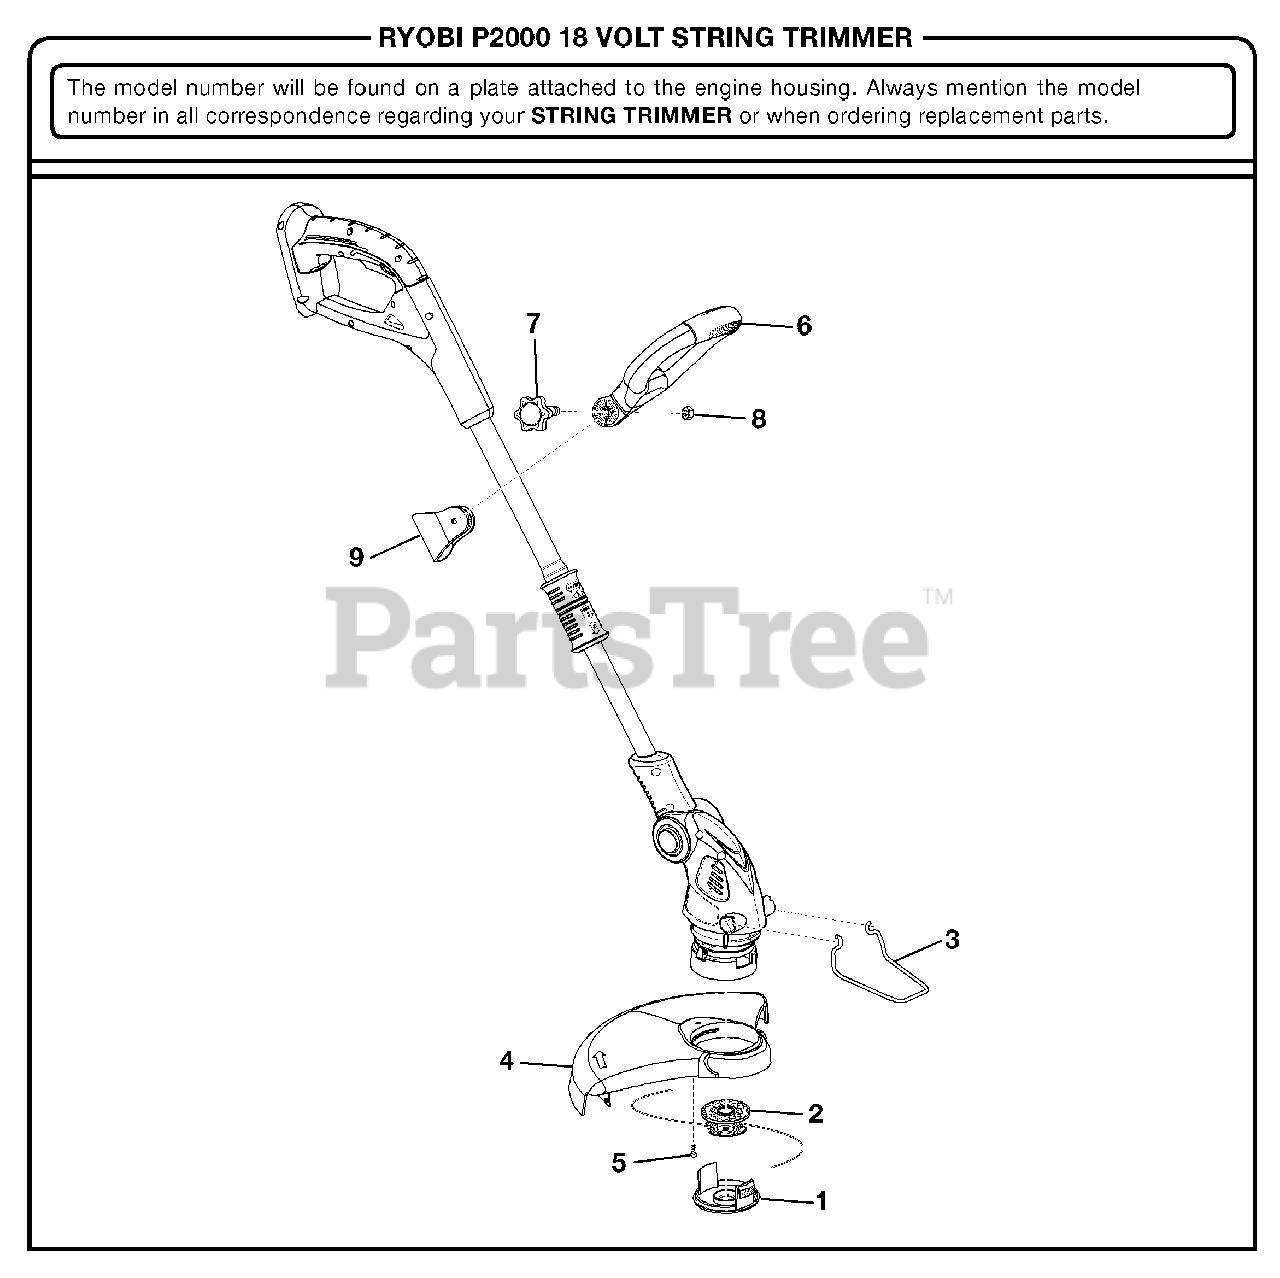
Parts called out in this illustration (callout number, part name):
1	Spool Cap
2	Spool with Line
3	Edger Guide
4	Guard with Cutter
5	Screw (M4 x 10 mm)
6	Front Handle
7	Knob Screw (M6)
8	Hex Nut (M6)
